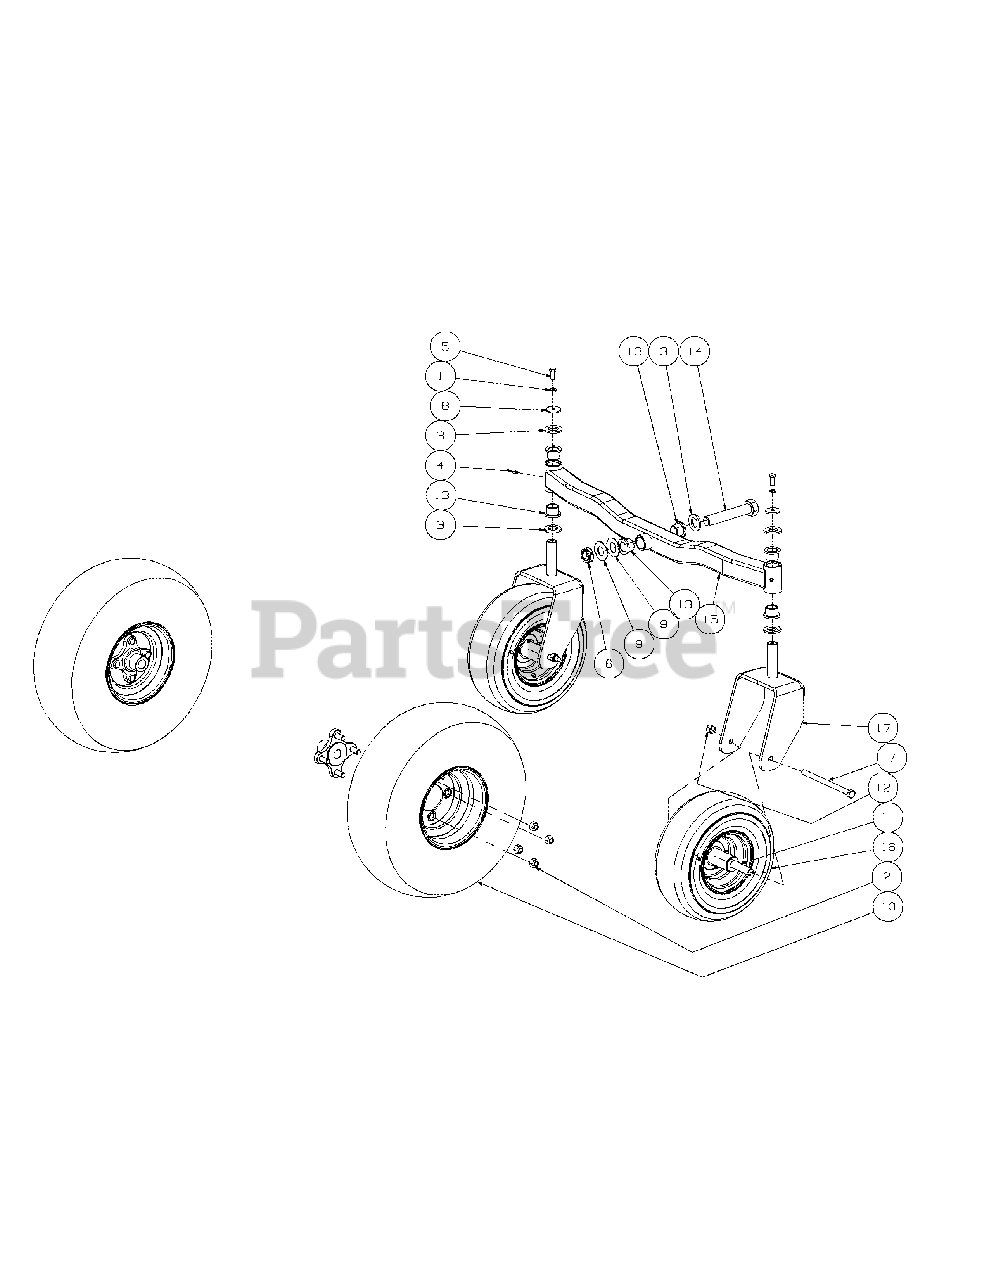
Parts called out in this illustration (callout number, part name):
1	Lock Washer, 3/8 Zinc
2	Lug Nut, 1/2-20
3	Washer Special
4	Grease Fitting, 1/4-28 x 3/16
5	Hex Cap Screw, 3/8-16 x .88
6	Nut Jam, 1.0-14, Nylon Insert
7	Hex Cap Screw, 1/2-20 x 7.50
8	Flat Washer, .390 x 1.5 x .134
9	Flat Washer, 1.00 ID x 2.25 OD x ,075
10	Wheel Assembly, 20 x 8-10 NHS
11	Wheel Spacer
12	Lock Nut, Nylon Insert, 1/2-20
13	Flange Bearing, 1.001 x 1.25
14	Hex Cap Screw, 1-14 x 5.5
15	Front Axle Assembly
16	Wheel Assembly 13 x 5.00-6
17	Castor Wheel Mounting Bracket
